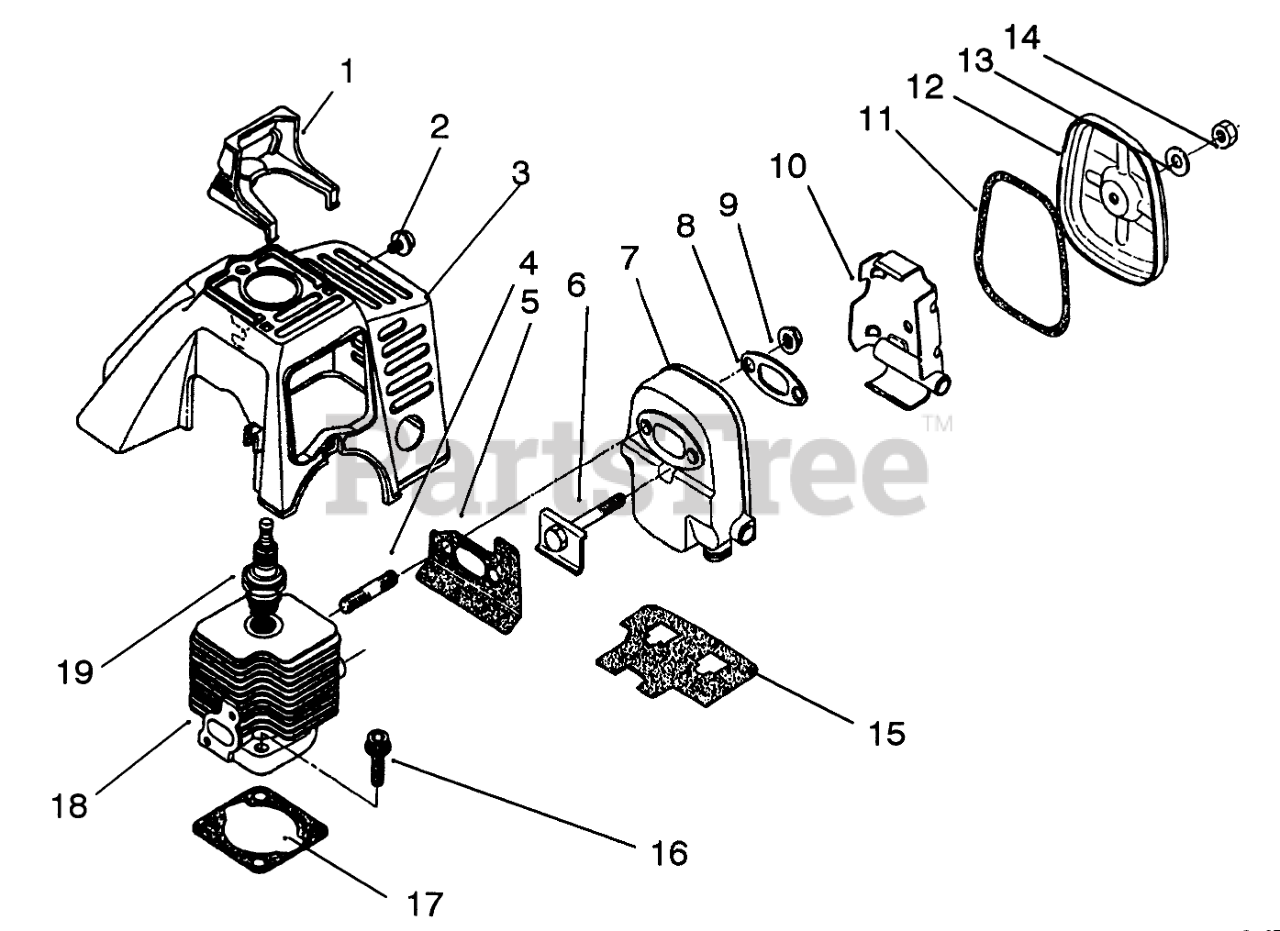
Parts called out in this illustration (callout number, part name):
1	SPARK PLUG GUARD
2	SCREW & WASHERE
3	TOP COVER
5	MUFFLER GASKET
7	BODY MUFFLER
8	PLATE
10	PLATE
11	GASKET
12	MUFFLER LID
13	GASKET
15	BAFFLE GASKET
16	FLANGE BOLT
17	CYL GASKET
18	CYLINDER
19	Plug-Spark
